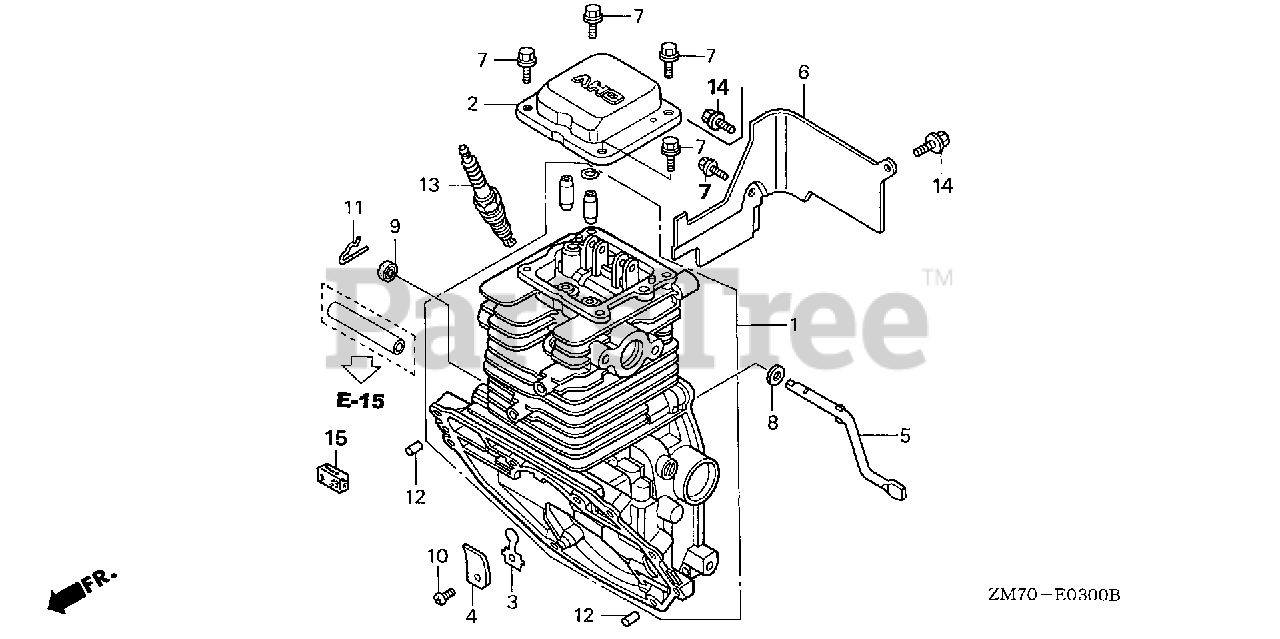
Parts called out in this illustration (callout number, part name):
2	COVER, HEAD
3	VALVE, OIL OUTLET
4	PLATE, STOPPER
5	SHAFT, GOVERNOR ARM
7	BOLT, FLANGE (5X12)
8	WASHER (5.2X9)
9	OIL SEAL (5X11X5)
10	SCREW, PAN (3X5)
11	PIN, LOCK (6MM)
12	ROLLER (6X15)
13	SPARK PLUG (U14FSR-UB)
13	SPARK PLUG (CR4HSB)
13	SPARK PLUG (CR5HSB)
14	BOLT, FLANGE (5X12)
